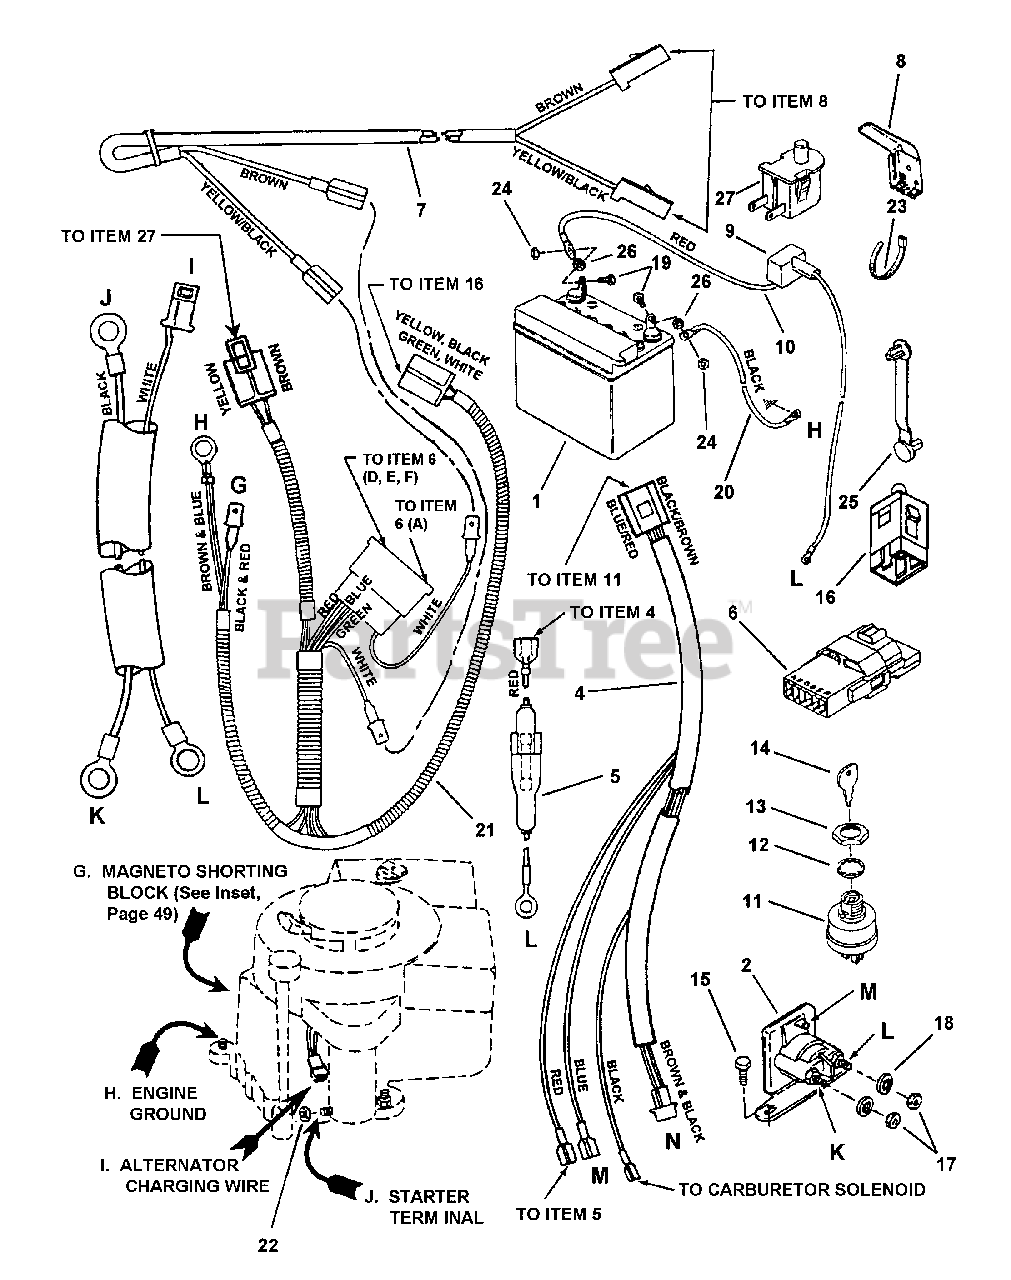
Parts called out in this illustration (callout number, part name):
1	KIT, 12V Dry Charge Battery
2	SOLENOID
4	HARNESS, Ignition Wiring (Briggs)
5	HOLDER, Fuse
6	INTERLOCK Module (Briggs)
7	HARNESS, (Deck Interlock Wiring)
8	SWITCH, Deck Interlock (NO)
9	COVER, Battery Cable
10	CABLE, Positive (Red)
11	SWITCH, Ignition-Afterfire Solenoid
12	WASHER, 5/8" Internal Tooth Lock
13	NUT, 5/8-32 Hex
14	KEY, Switch
15	SCREW, 1/4-20 x 1/2" Hex Washer Self-Tap
16	SWITCH, Operator Presence Control (OPC) Traction (NC/NO)
17	NUT, 1/4-20 Hex, Grade 5 or B
18	WASHER, 1/4" Internal Tooth Lock
19	SCREW, 1/4-20 x 5/8" Hex Head Cap, Grade 5
20	CABLE, Negative (15")
21	HARNESS, Operator Presence Control Wire
22	NUT, 1/4-20 Hex, Grade 5 or B
23	TIE, 7" Long Cable
24	NUT, 1/4-20 Hex Center Lock, Grade 5 or B
25	TIE, 2" Long Cable
26	RETAINER, 1/4" Bolt
27	SWITCH, Seat
